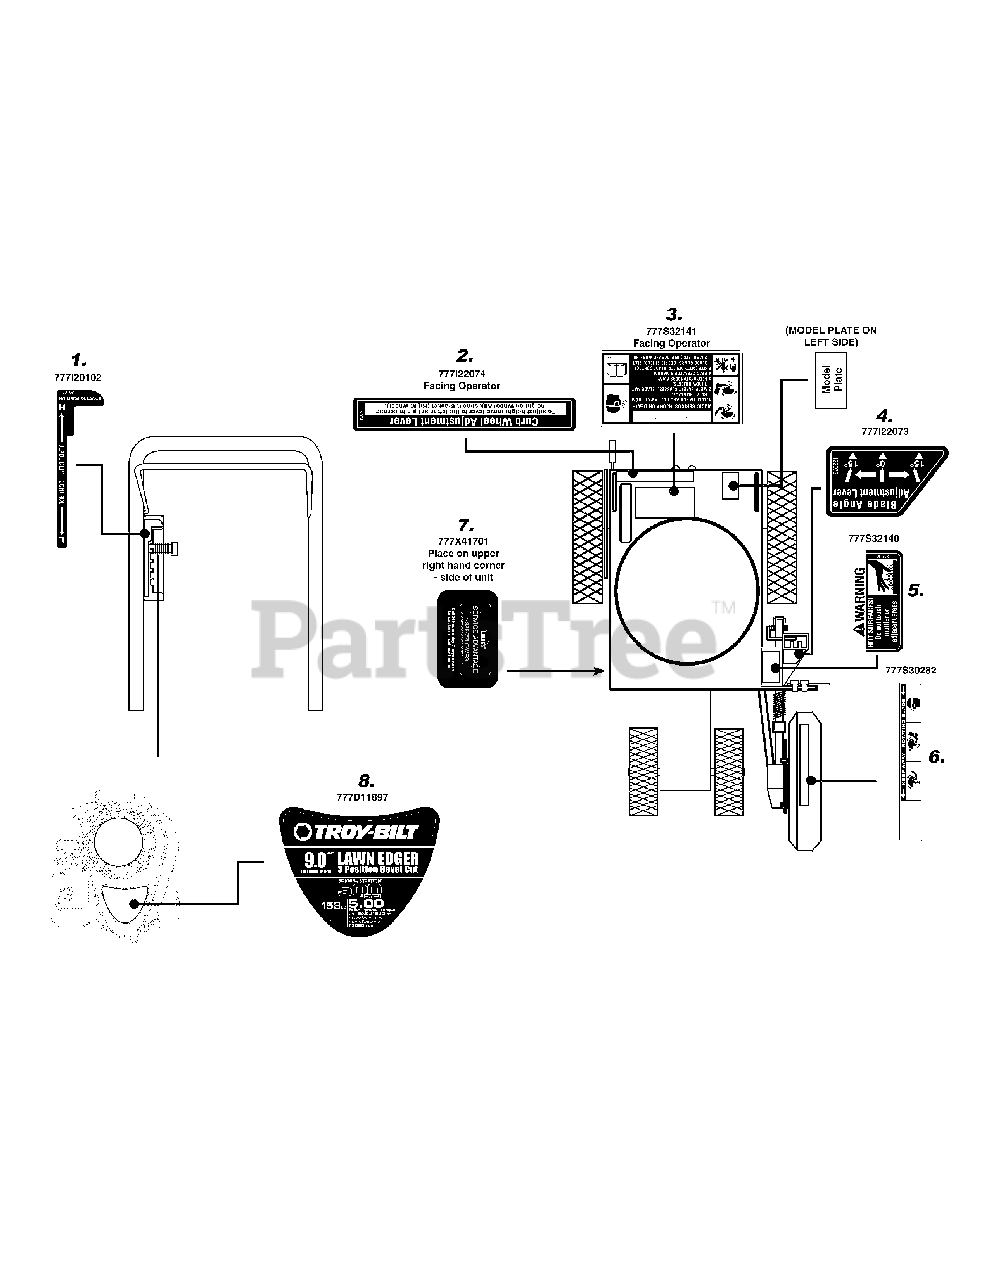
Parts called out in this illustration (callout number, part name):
1	LBL:BLADE DEPTH CNTRL (EDGER)
2	LBL:CURB WHEEL/ADJ LEVER
3	LBL:EDGER:REAR:DANGER
4	LBL:BLADE ADJ:EDGER
5	LBL:MUFFLER:HOT SURF:WRN
6	LBL:EDGR:BLD CVR SFTY(S30021)
7	LBL:LOWES SERVICE ADVANTAGE
8	LBL:TROY BILT
